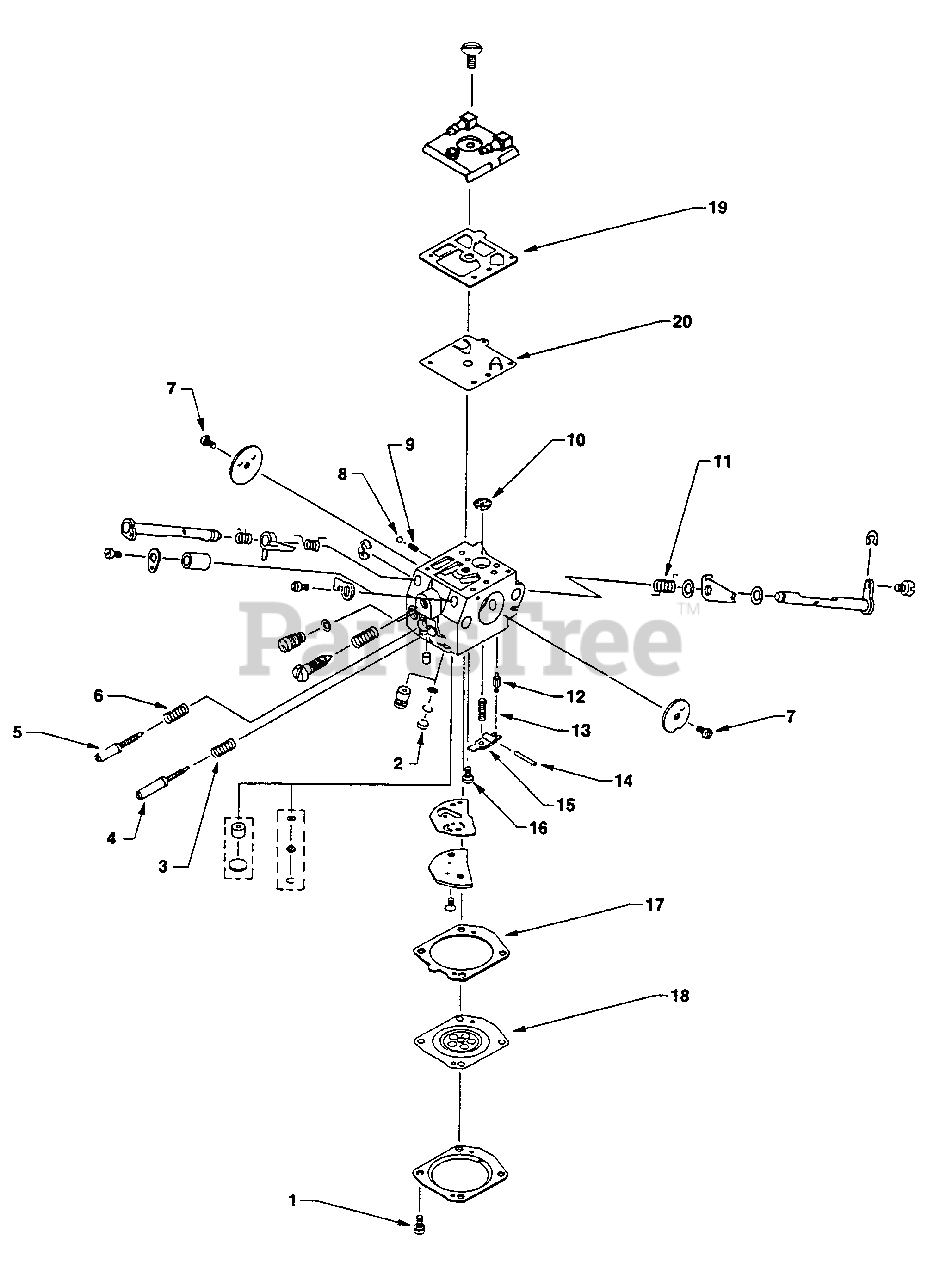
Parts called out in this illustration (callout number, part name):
1	Repair Kit
2	Repair Kit
3	Repair Kit
4	Repair Kit
5	Repair Kit
6	Repair Kit
7	Repair Kit
8	Repair Kit
9	Repair Kit
10	Repair Kit
11	Repair Kit
12	Repair Kit
13	Repair Kit
14	Repair Kit
15	Repair Kit
16	Repair Kit
17	Repair Kit
17	Gasket/Diaphragm Kit
18	Repair Kit
18	Gasket/Diaphragm Kit
19	Repair Kit
19	Gasket/Diaphragm Kit
20	Repair Kit
20	Gasket/Diaphragm Kit
